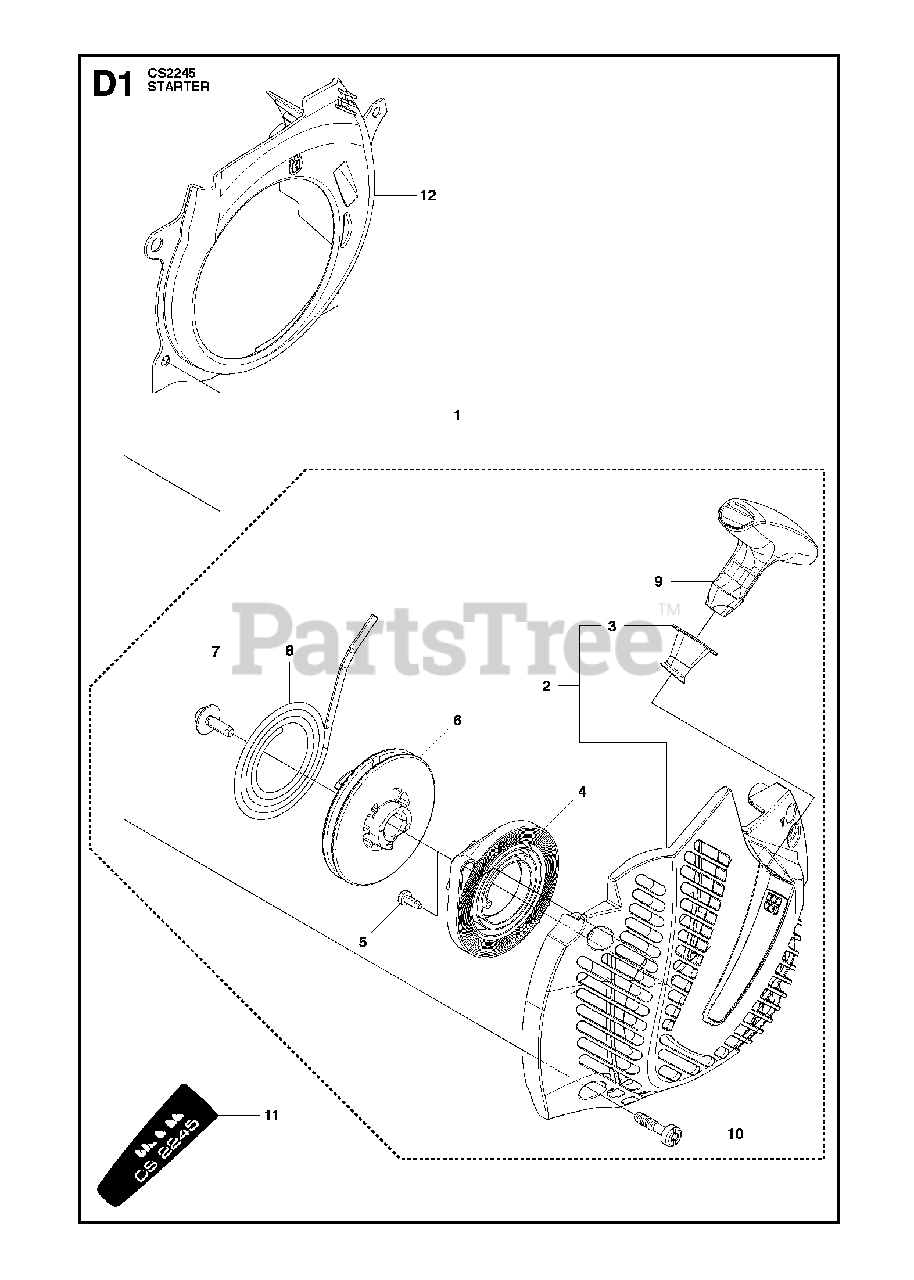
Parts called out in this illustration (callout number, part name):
1	STARTER ASSY
2	STARTER HOUSING
3	SLEEVE
4	SPRING CASSETTE ASSY
5	SCREW
6	PULLEY
7	SCREW
8	STARTER ROPE
9	STARTER HANDLE
10	SCREW
12	COOLING AIR CONDUCTOR
